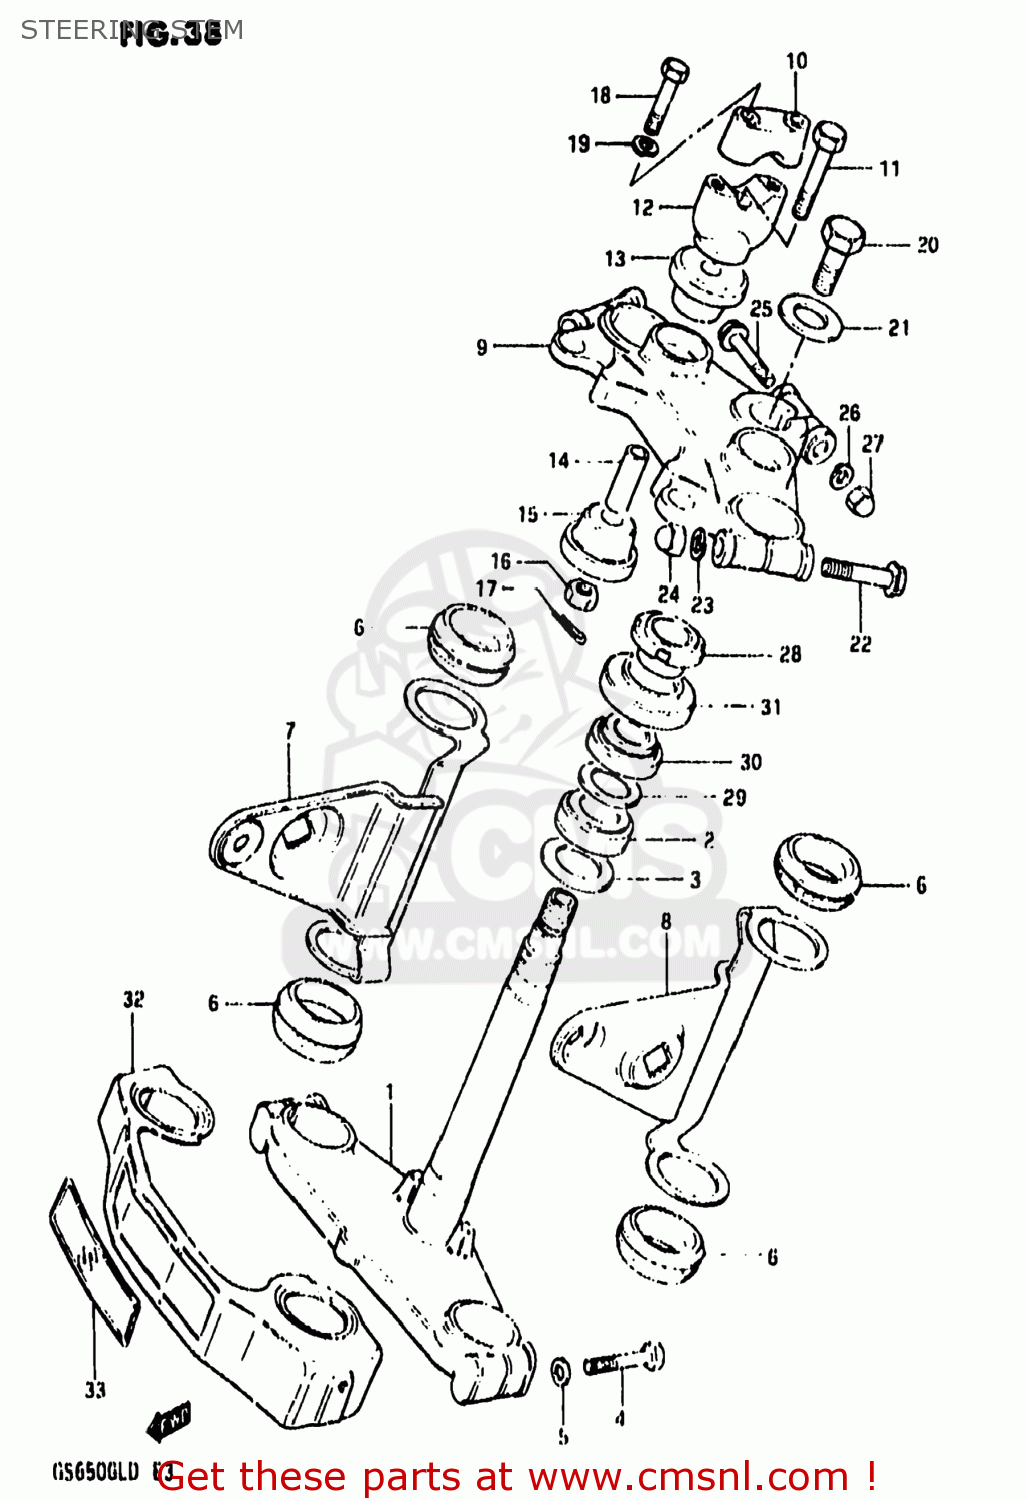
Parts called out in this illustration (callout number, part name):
1	STEM,STEERING
2	BEARING
3	WASHER,THRUST
4	BOLT 8X45
5	WASHER,LOCK,8.
6	CUSHION,HEADLAMP BRACKET
7	BRACKET,HEADLAMP,RIGHT
8	BRACKET,HEADLAMP,LEFT
9	HEAD,STEERING STEM
10	HOLDER,HANDLE UPR
11	BOLT(10X78)
12	CLAMP,HANDLEBAR,LOWER
13	CUSHION,UPR
14	SPACER(10.2X14X46)
15	CUSHION
16	NUT
17	COTTER PIN
18	BOLT
19	LOCK WASHER
20	BOLT(12X20)
21	WASHER
22	BOLT 10X55
23	LOCK WASHER
24	NUT
25	BOLT
26	LOCK WASHER
27	NUT,M8X1.25X12
28	NUT,STEERING STEM
29	WASHER(18.5X24X1)
30	TAPER,ROLLER BEARING
31	DUST SEAL,STEERING UPR
32	COVER,FRONT FORK
33	EMBLEM,FRONT FORK COVER
